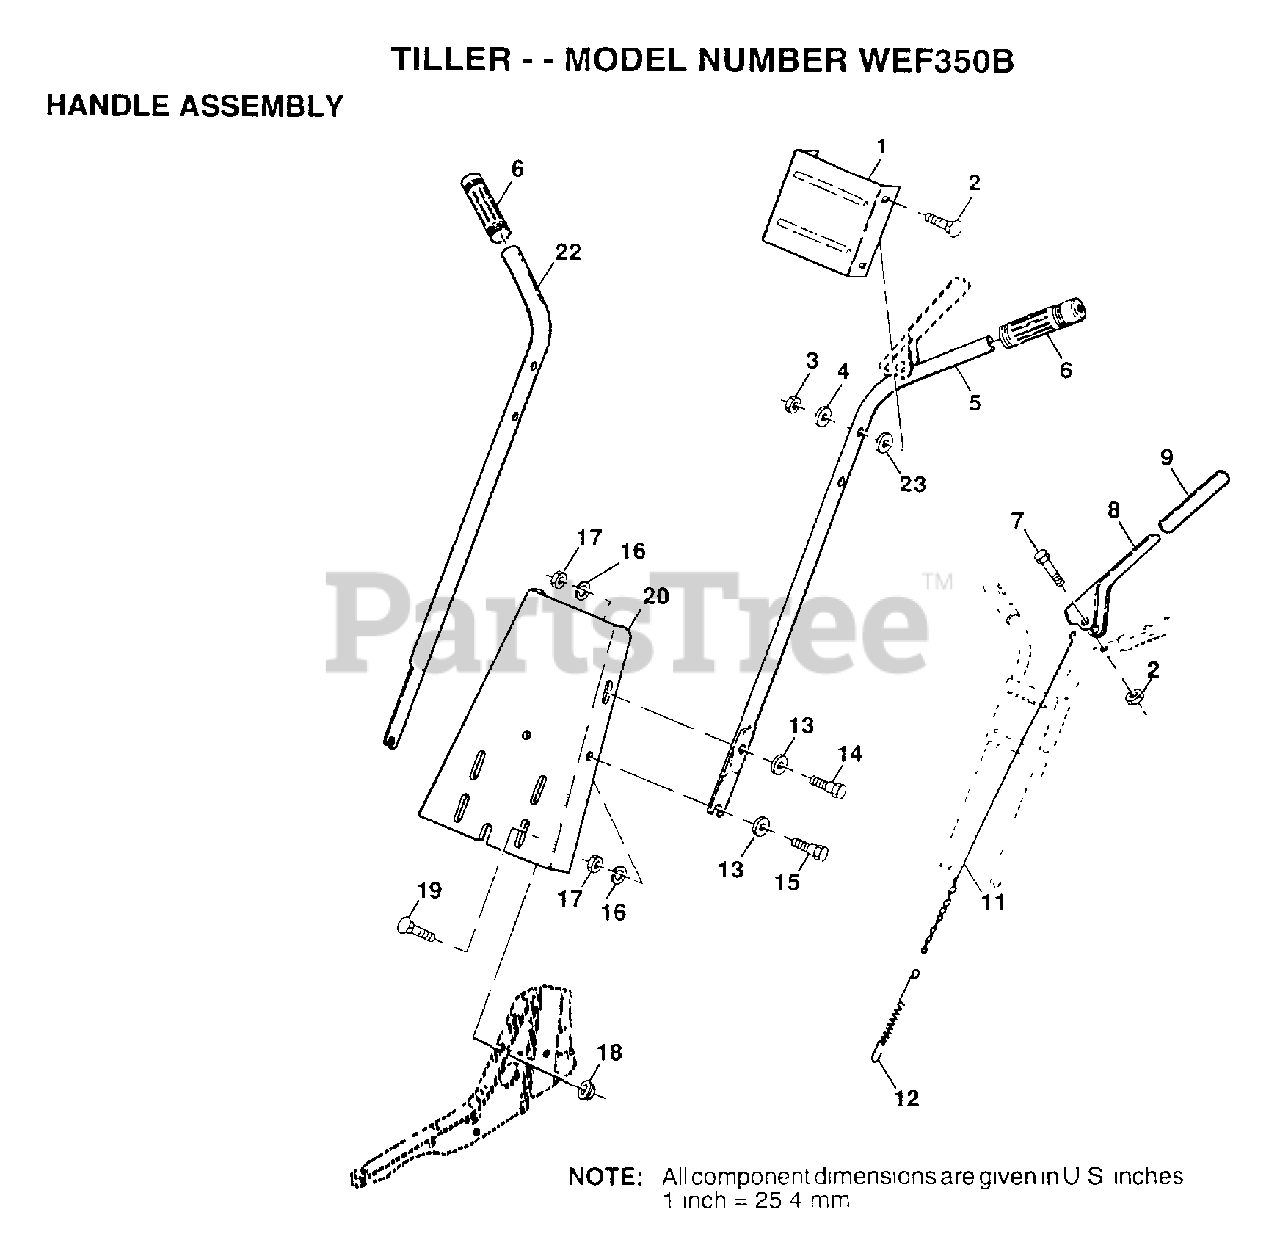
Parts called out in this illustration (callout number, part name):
1	PANEL.CNTRL.HDLE.
2	BOLT
4	WASHER
5	HANDLE LH
7	BOLT.HEX.5/16-1.5
9	GRIP T
12	SPRING EXT TI
13	WASHER
15	BOLT
16	LOCKWASHER
17	NUT.HEX.5/16-18
18	NUT
19	BOLT
20	PANEL.HANDLE.TILL
21	BOLT CRT
22	HANDLE RH
23	WASHER
